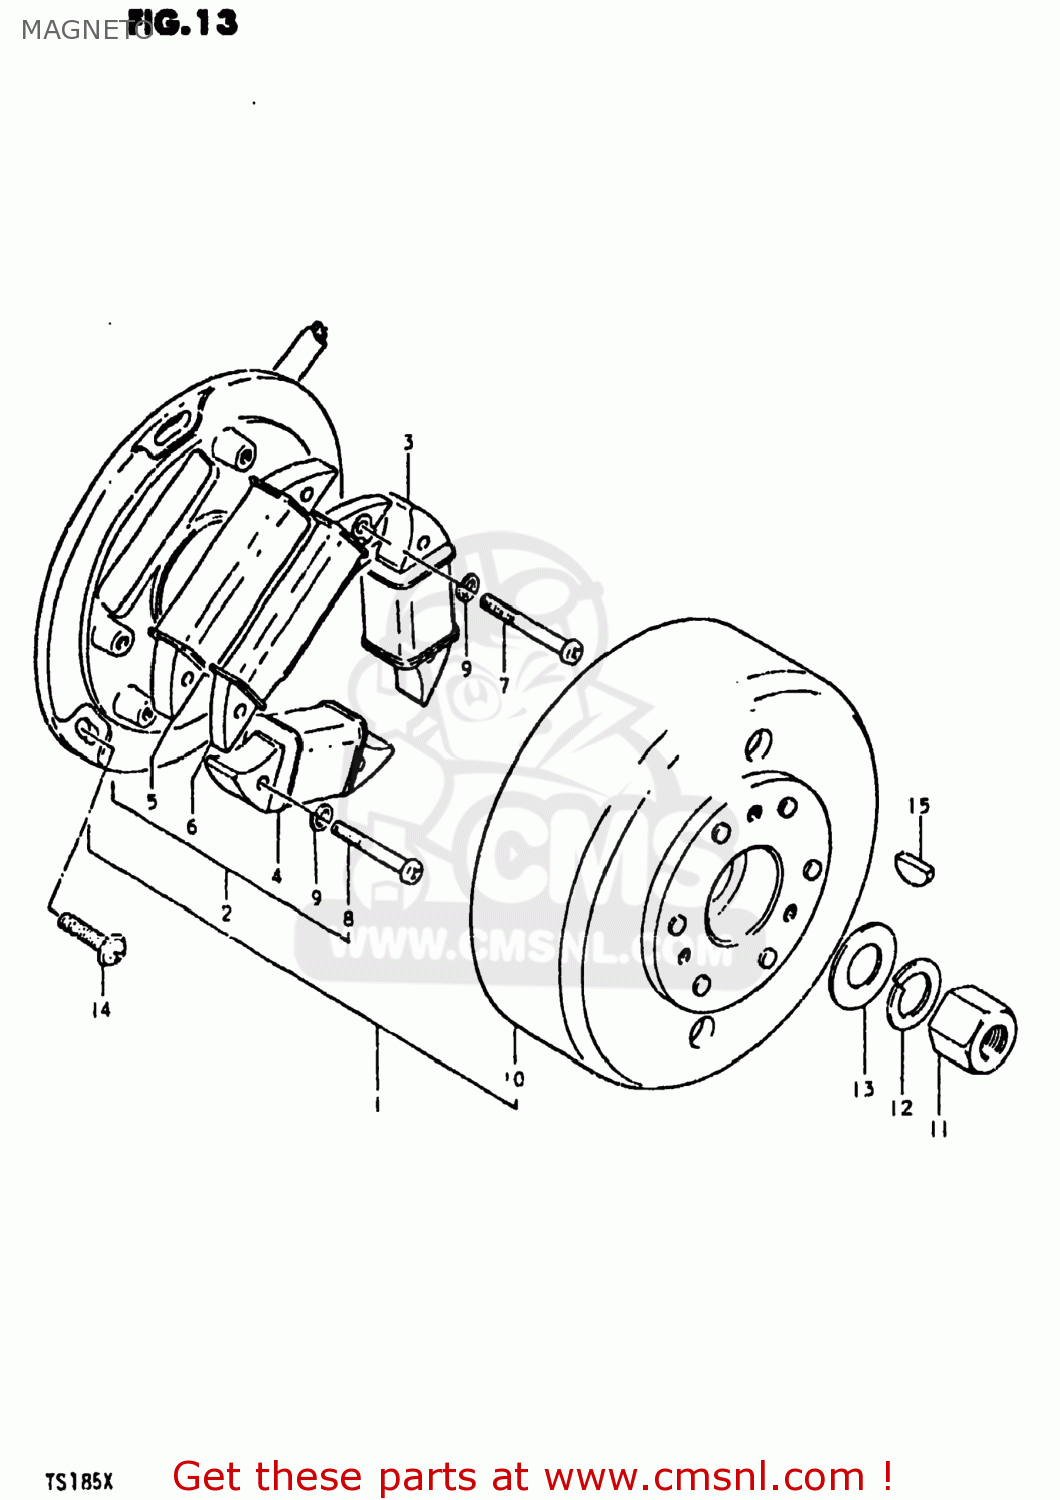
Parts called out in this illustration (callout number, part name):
1	MAGNETO ASSEMBLY
2	STATOR ASSEMBLY
3	COIL,CHARGE
4	COIL,LIGHTING
5	COIL,PRIMARY
6	COIL,PULSER
7	SCREW
8	SCREW 5X20
9	LOCK WASHER
10	ROTOR,FLYWHEEL
11	NUT
12	LOCK WASHER
13	WASHER(14X27X3)
14	SCREW(5X14)
15	KEY 4MM
